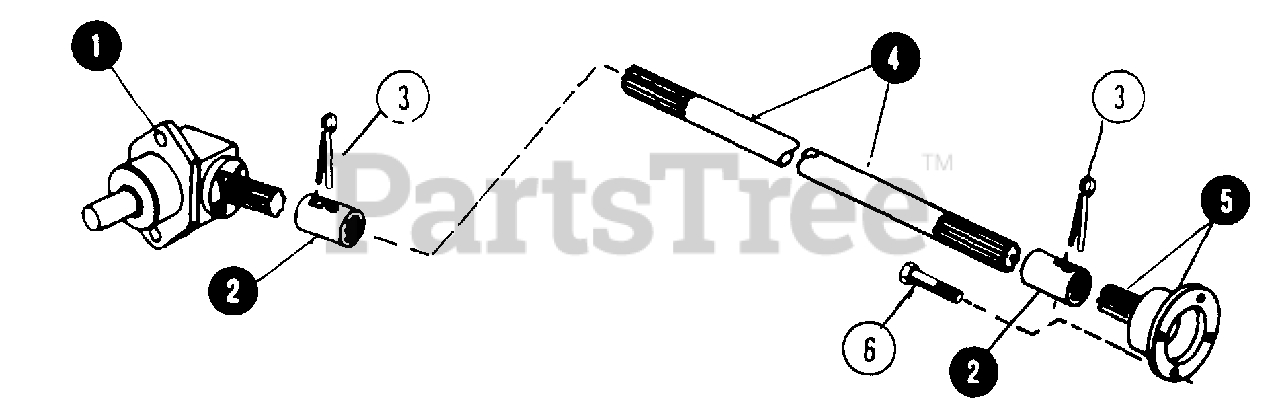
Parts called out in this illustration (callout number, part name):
1	GEARBOX ASSEMBLY - COMPLETE
2	COUPLING, DRIVE SHAFT
3	COTTER-PIN, 1/4 x 1-1/2
4	SHAFT, FRONT DRIVE
5	ADAPTER, ENGINE DRIVE
6	BOLT, 3/8C x 1 SOCKET HEAD
